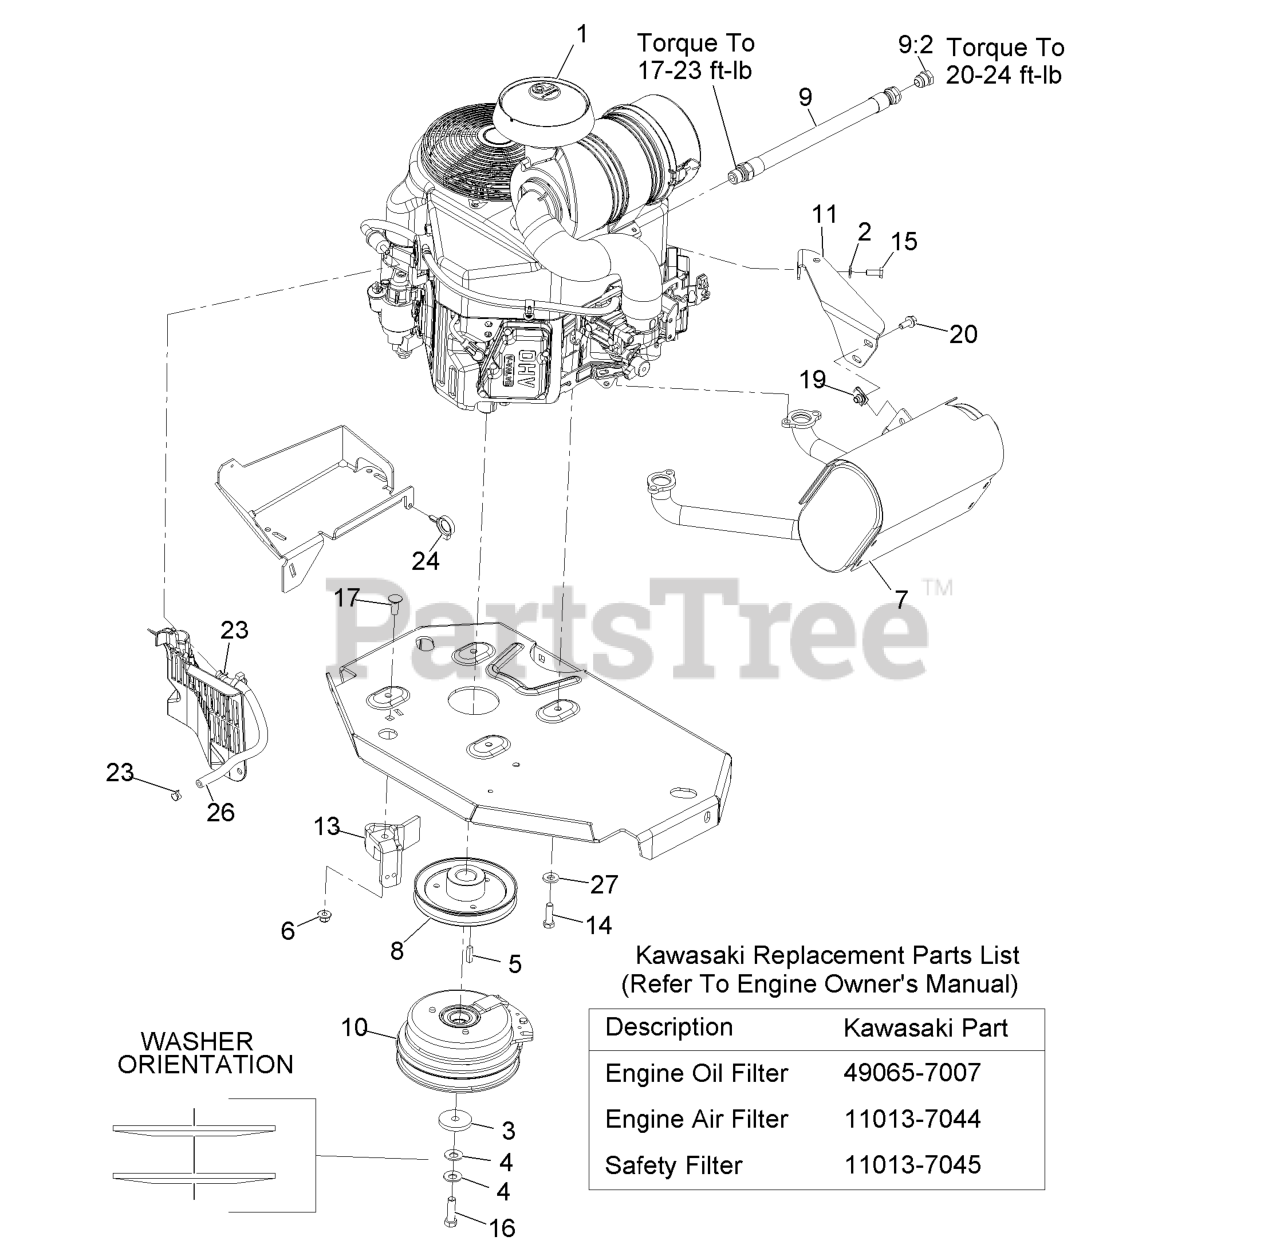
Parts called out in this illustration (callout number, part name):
2	WASHER-SPRING
3	WASHER-CLUTCH
4	WASHER-SPRING
6	NUT-HF, NI
7	MUFFLER
8	SHEAVE
10	CLUTCH KIT
11	BRACKET-MUFFLER
13	CLUTCH-ANCHOR
14	SCREW-HH
15	SCREW-HH
16	SCREW-HH 7/16-20 X 1 1/2 W/LOCTITE
17	SCREW-CARR
20	SCREW-HHF
23	CLAMP-HOSE
24	CLAMP-HOSE
26	HOSE-FUEL
27	WASHER-BELLEVILLE
